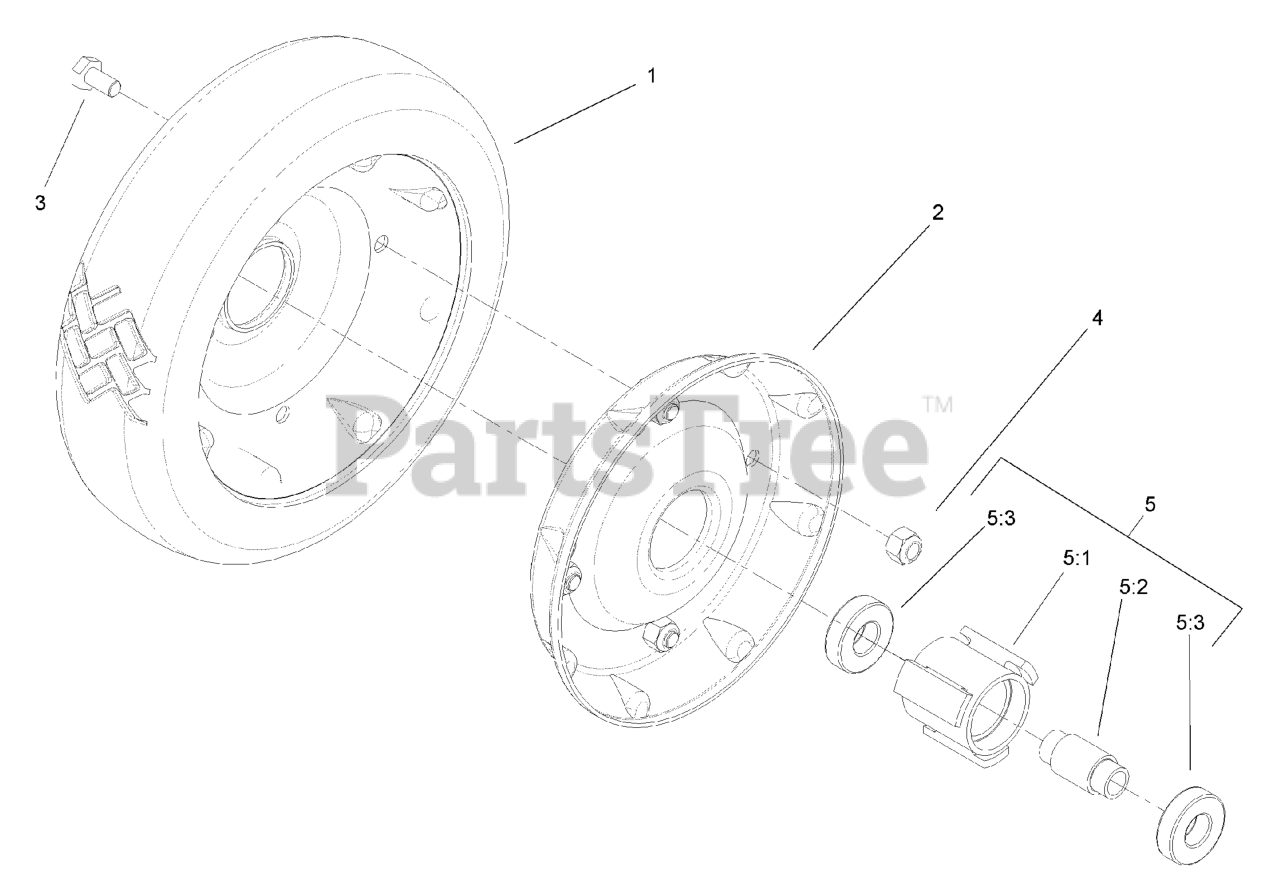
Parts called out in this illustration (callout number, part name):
3	SCREW-HH
4	NUT-LOCK, NI
5	Hub And Bearing Asm
5:1	HUB-BEARING
5:2	SPACER-BEARING
5:3	BEARING-WHEEL
